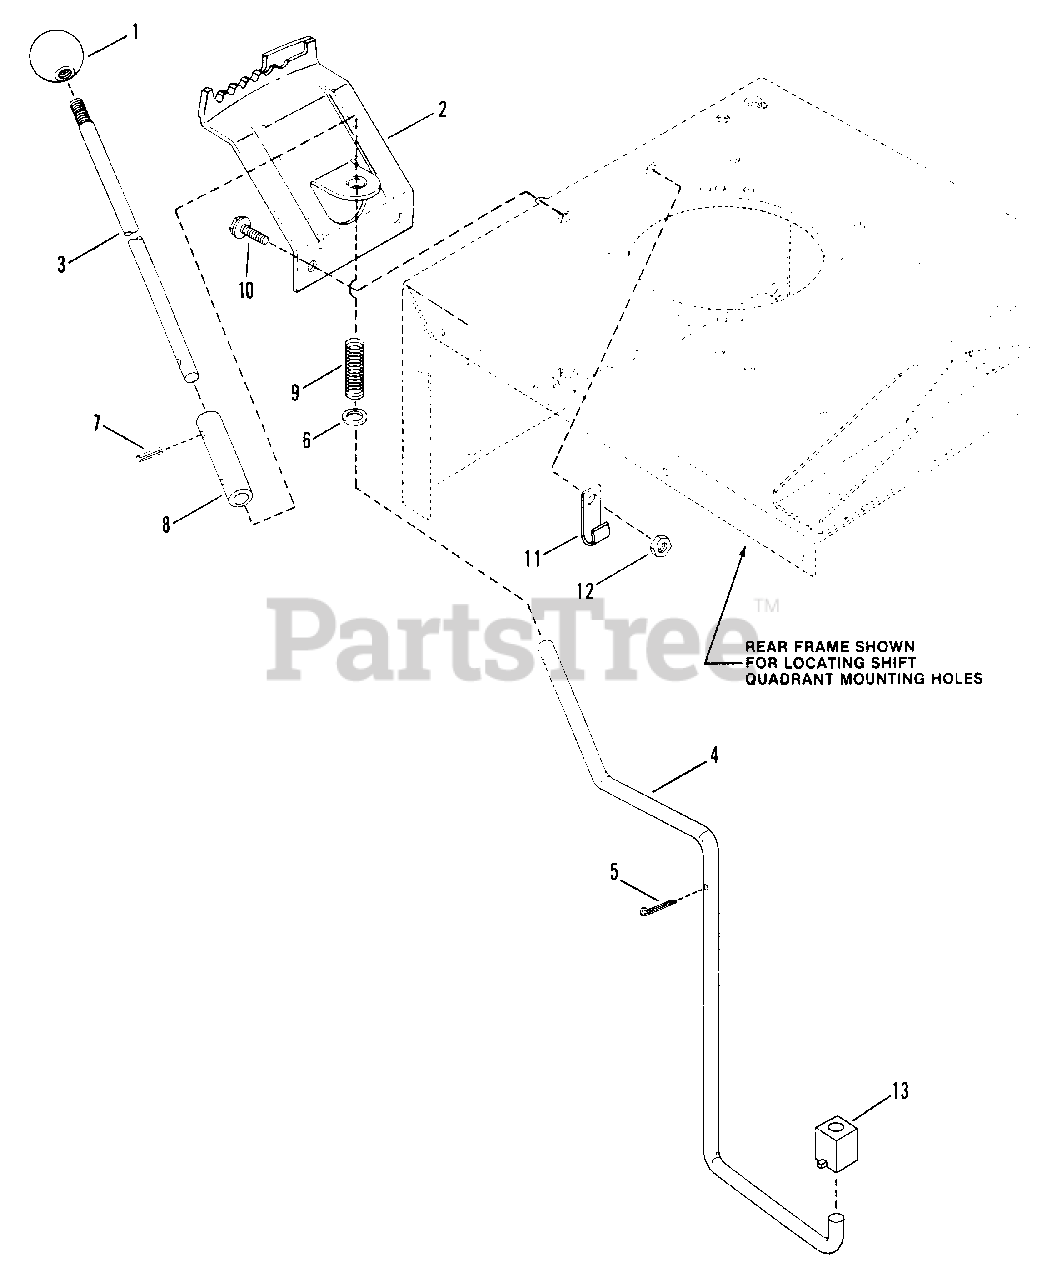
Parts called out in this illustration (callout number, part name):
1	KNOB, Shift Lever, Upper
2	QUADRANT, Shift
3	LEVER, Shift, Upper
4	LEVER, Shift, Lower
5	COTTER-PIN, 3/32 x 1"
6	WASHER, Shim
7	ROLL-PIN, 3/16 x 3/4"
8	CONNECTOR, Shift Lever
9	SPRING
10	SCREW, 5/16-18 x 3/4" H.W.H. Self-Tapping
11	CLIP, Harness
12	NUT, 5/16-18 Hex Center Lock
13	BLOCK, Wear
